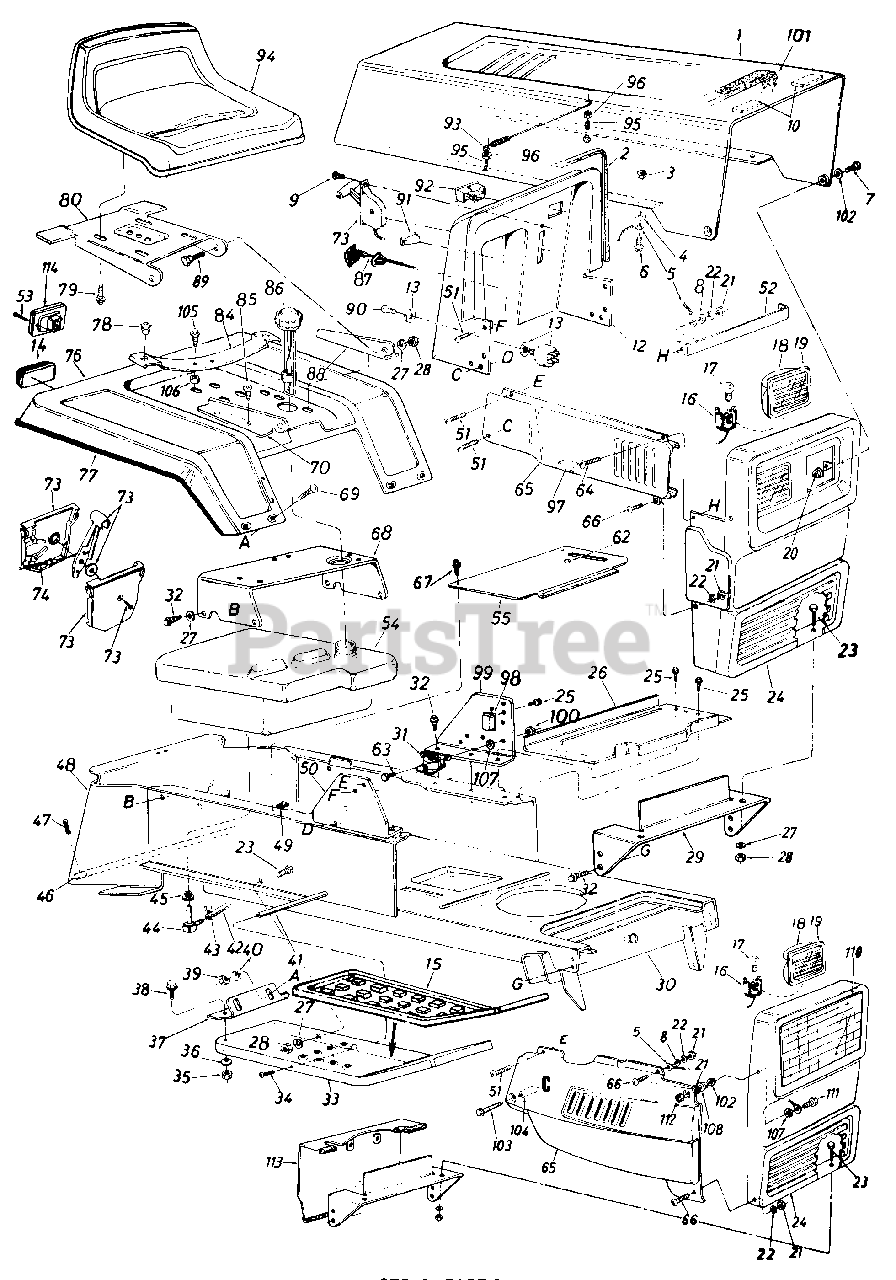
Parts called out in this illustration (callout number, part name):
3	Hex Sems Nut #10-24 Thd.
4	Fl-Wash. .20" I.D. x .41" O.D.
5	Hood Stop
6	Truss Scr. #10-24 x .5"*
7	Shld. Bolt .375 Dia. x .125
8	Fl-Wash. 1/4" I.D.*
9	Truss Mach. AB-Tap Scr. #10-24 x .5" Lg.
10	Foam Strip
14	Reflector
15	Rubber Foot Pad
16	Socket
17	Lamp
18	Headlight Housing
19	Lens
20	L-Nut 1/4-28 Thd.
21	Hex Nut 1/4-20 Thd.*
22	L-Wash. 1/4" I.D.*
23	Hex Bolt 5/16-18 x .75" Lg.*
24	Grille
26	Battery Plate
27	L-Wash. 5/16" I.D.*
28	Hex Nut 5/16-18 Thd.*
29	Grille Mounting Bracket
30	Lower Frame Ass'y.
31	Solenoid
32	Hex Thd. Rolling Scr. 5/16-24 x .75" Lg.
35	Hex Nut 5/16-18 Thd.*
36	Bell-Wash. .34" I.D.
39	Hex Nut 1/4-20 Thd.*
40	L-Wash. 1/4" I.D.*
41	Running Board Rod
42	Fuel Line 44" Lg.
43	Hose Clamp 3/8"
44	90ø Elbow
45	Bushing
46	Hitch Rod
47	Internal Cotter Pin
50	Dash Support Brkt.-R.H.
51	Hex Tap Scr. 1/4 x .75" Lg.
52	Tie Strap-Grille Side Panel
53	Truss AB-Tap Scr. #6 x .62"
54	Fuel Tank
55	Transmission Cover Ass'y.
62	Snap Bushing
63	Hex Bolt 1/4-20 x .50" Lg.*
64	Truss Hd. Scr. 1/4-20 x .75"*
67	Truss B-Tap Scr. #10 x .5"
68	Seat Mounting Channel
69	Carriage Bolt 1/4-20 x .50"*
70	Seat Bracket-R.H.
73	Throttle Control Box Ass'y.
74	Throttle Control Wire
78	Grommet
79	Hex AB-Tap Scr. 3/8 x .75"
80	Seat Pivot Bracket
84	Seat Spring
85	Hex Self-Tap Scr. 5/16-18 x .5"
86	Gas Cap w/Gauge
87	Choke Control Comp.
88	Seat Bracket-L.H.
89	Shld. Bolt .437" Dia. x .162"
90	Ignition Key
91	Light Switch
92	Ammeter
93	Hood Spring
94	Seat Ass'y.
95	Hex Bolt #10-24 x 1.0" Lg.
96	Hex Sems Nut #10-24
97	Rubber Strip 1/2" Sq. x 2-1/2"
98	Circuit Breaker
99	Dash Support Brkt.-L.H.
100	Hex Sems Nut 1/4-20 Thd.
101	PVC Foam
102	Washer .34" I.D. x .62" O.D.
103	Hex Tap Scr. 1/4-20 x 1.75"
104	Spacer .255" I.D.
105	Hex Tap Scr. 5/16-18 x 1.25"
106	Spacer.38" I.D.
107	Ext. L-Wash. 1/4" I.D.
108	Shld. Spacer .125" Lg.
110	Headlight Bezel
111	Hex Bolt 1/4-20 x .88" Lg.
112	Acorn Nut 1/4-20 Thd
113	Baffle Ass'y. Comp.
114	Taillight
